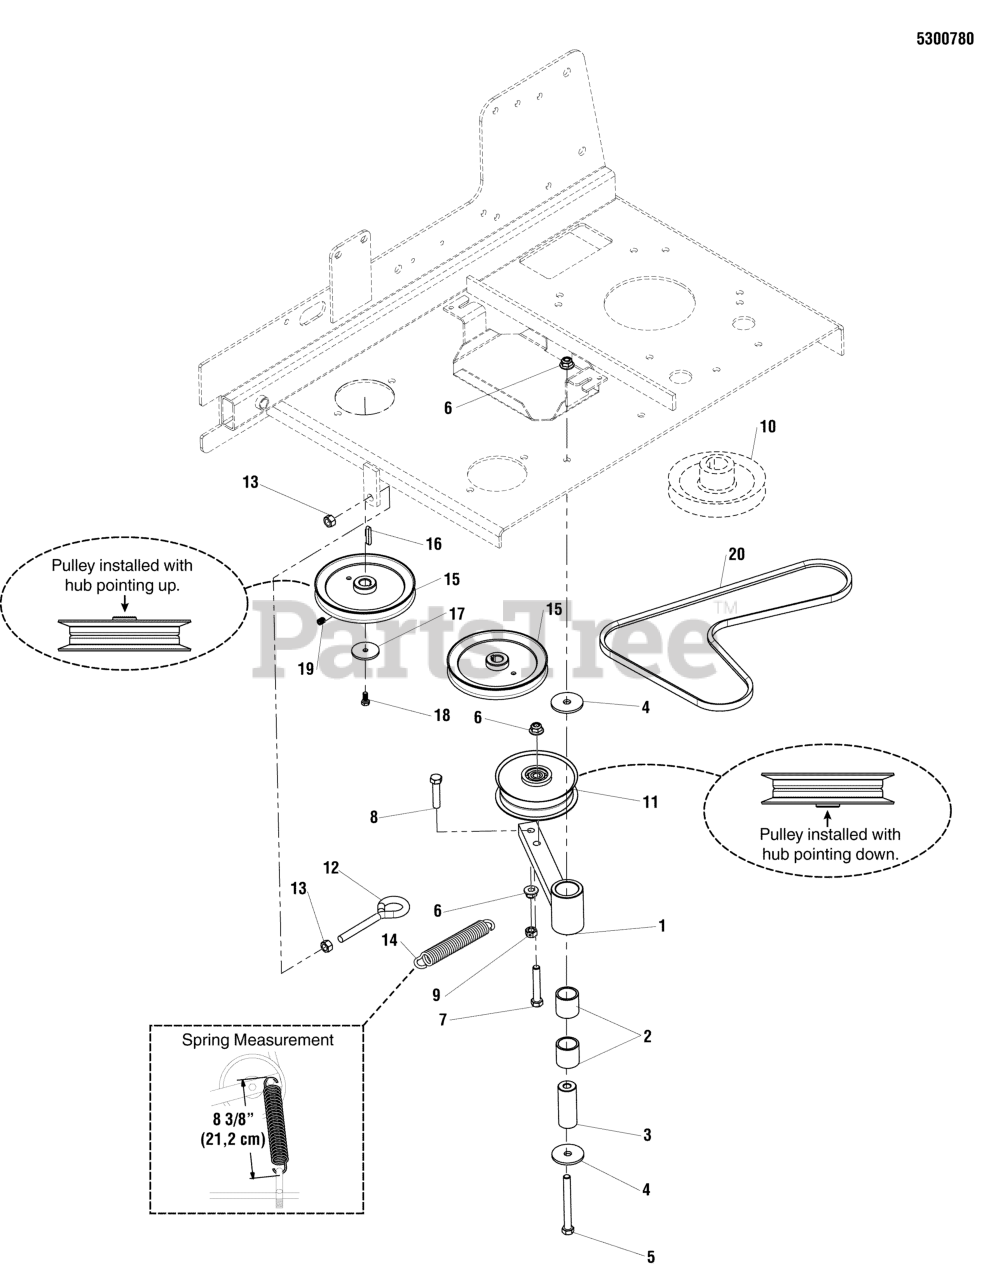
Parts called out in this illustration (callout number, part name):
1	See "PUMP DRIVE [Cast Idler Arm for replacing Steel Pump Drive Idler Arm]"
2	BUSHING, BRASS, 1.25X1X1.25
3	SPACER, .39 X 1.00 X 2.55, SS
4	WASHER, .41 X 1.75 X .14
5	BOLT, 3/8-16 X 3-1/2" GD5 CZ
6	NUT, 3/8-16 HEX NYLOCK FLANGE
7	BOLT, 3/8-16 X 2-1/4" GD5 CZ
8	BOLT, 3/8-16 X 1-3/4" GD5 CZ
9	NUT, 3/8-16 HEX SIDE LOCK
10	PULLEY CRANKSHAFT (SEE ENGINE & PTO GROUP)
11	PULLEY, FLAT IDLER, 4.06 X .75 W
12	EYEBOLT, 3/8-16 X 4, 2.13THRD, .75EYE, C
13	NUT, 3/8-16 HEX
14	SPRING, EXTENSION, SWIVEL END
15	PULLEY, PUMP DRIVE
16	KEY, 5MM SQ. W/ RADIUS
17	WASHER, .265 X 1.50 X .109, YZ
18	CAPSCREW,HEX HEAD M6-1.0X 14MM
19	SET SCREW, 5/16-18 X 3/8, KNURL, W/PATCH
20	BELT,#7-9502, B-SECT - EL 67.8, HYDRO
